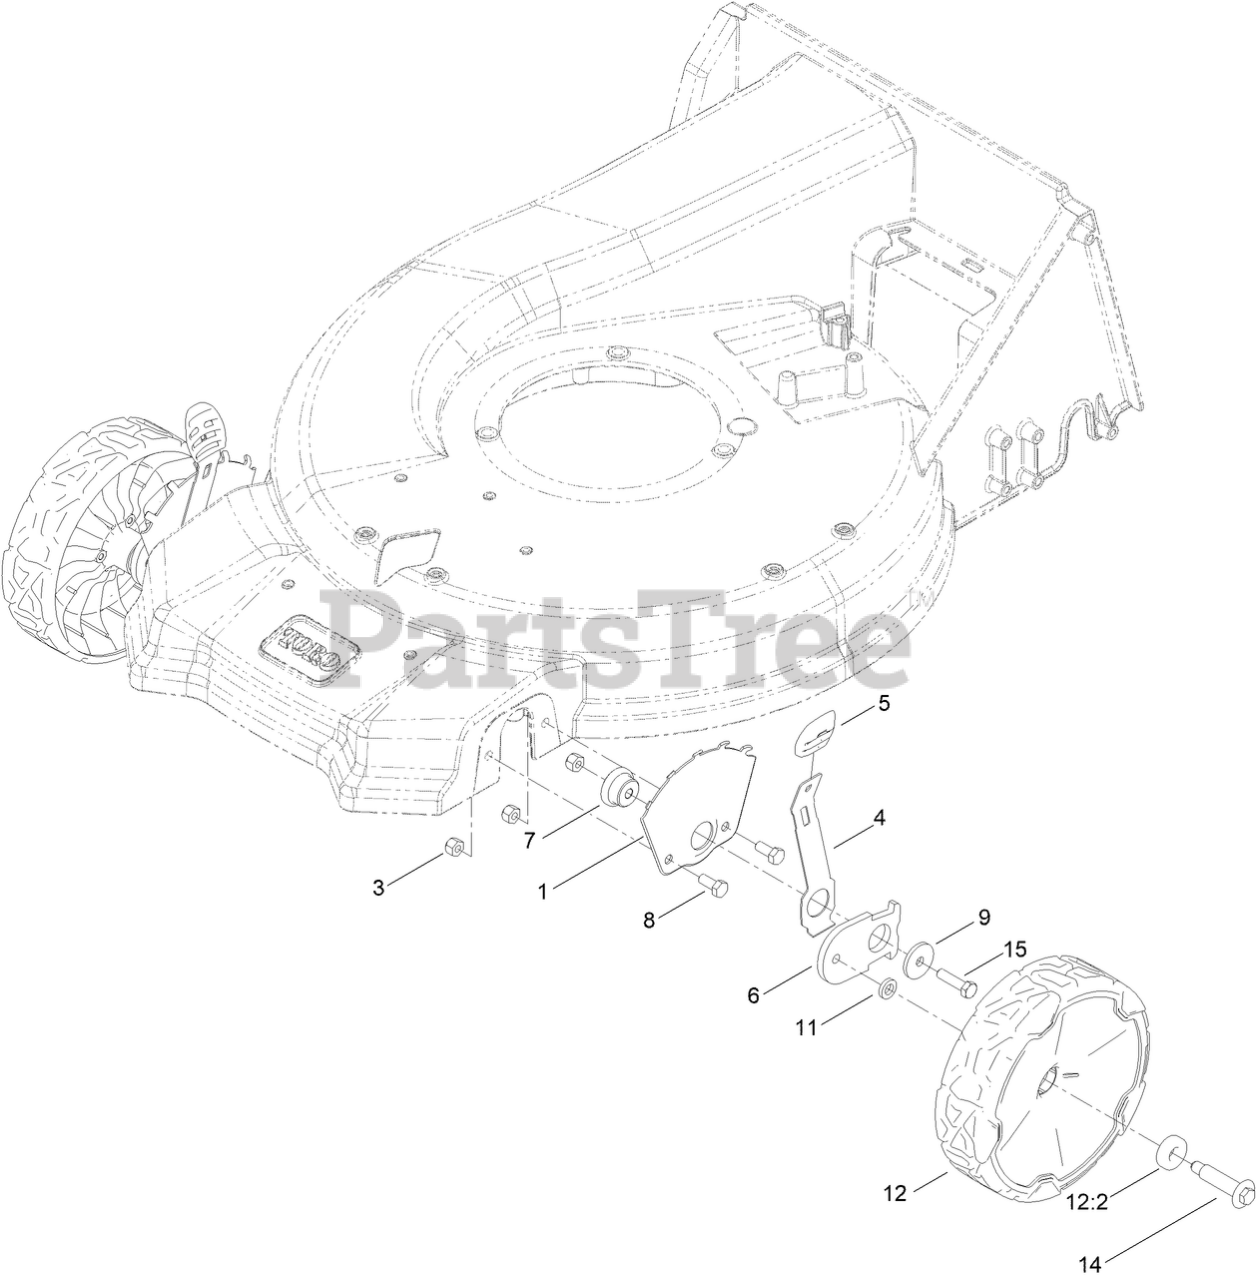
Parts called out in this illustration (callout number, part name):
1	PLATE-HOC,FRONT FSVQ WEDNESDAY
3	NUT-LOCK, NI
4	ARM-SPRING
5	KNOB-LEVER, HOC
6	ARM-PIVOT, FRONT
7	BUSHING-MOUNT, HOC
8	SCREW-HH
9	WASHER-FLAT
11	WASHER-WHEEL BOLT
12	ASM-WHEEL, 8" (BEARINGS)
12:2	BEARING-WHEEL
14	WHEEL BOLT
15	SCREW-HH
